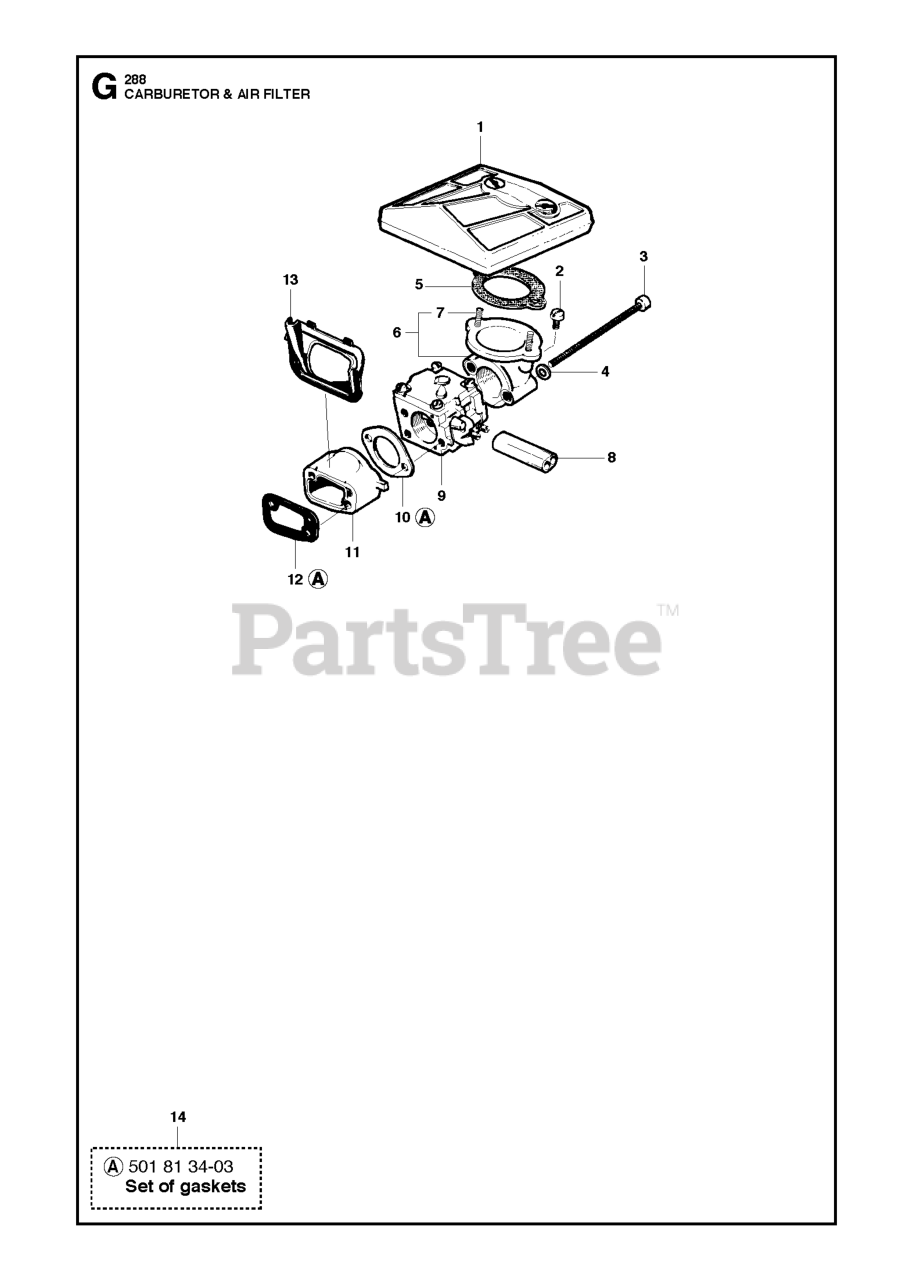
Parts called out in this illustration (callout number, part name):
1	AIR FILTER - FELT
1	AIR FILTER
2	SCREW M5 X 10
4	SPRING WASHER 5.3X10
6	AIR FILTER ATTACHMENT
9	CARBURETOR
13	SEALING COLLAR
14	GASKET KIT
